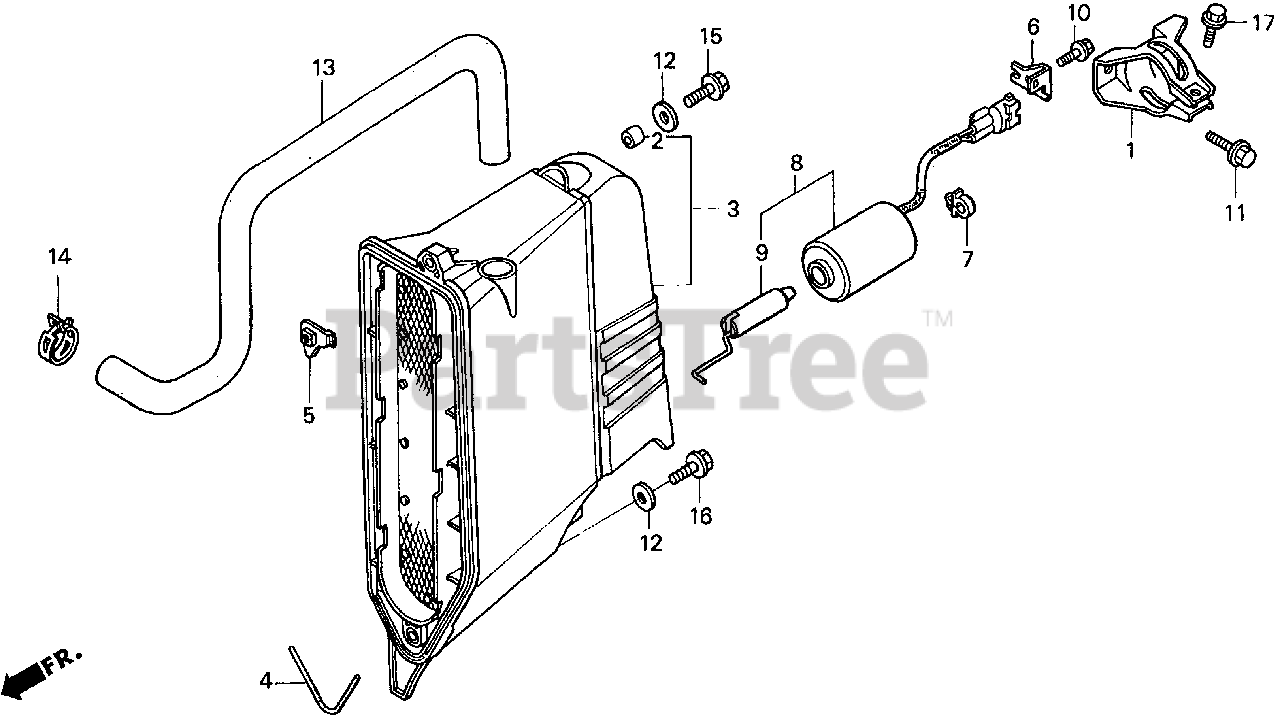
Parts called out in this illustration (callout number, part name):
2	COLLAR, DISTANCE
3	COVER, MUFFLER
4	GASKET, MUFFLER COVER
5	NUT, MUFFLER COVER
12	WASHER (6.5X18)
13	TUBE, BREATHER
14	CLAMP, TUBE (D17)
15	BOLT, FLANGE (6X25)
16	BOLT, FLANGE (6X40)
